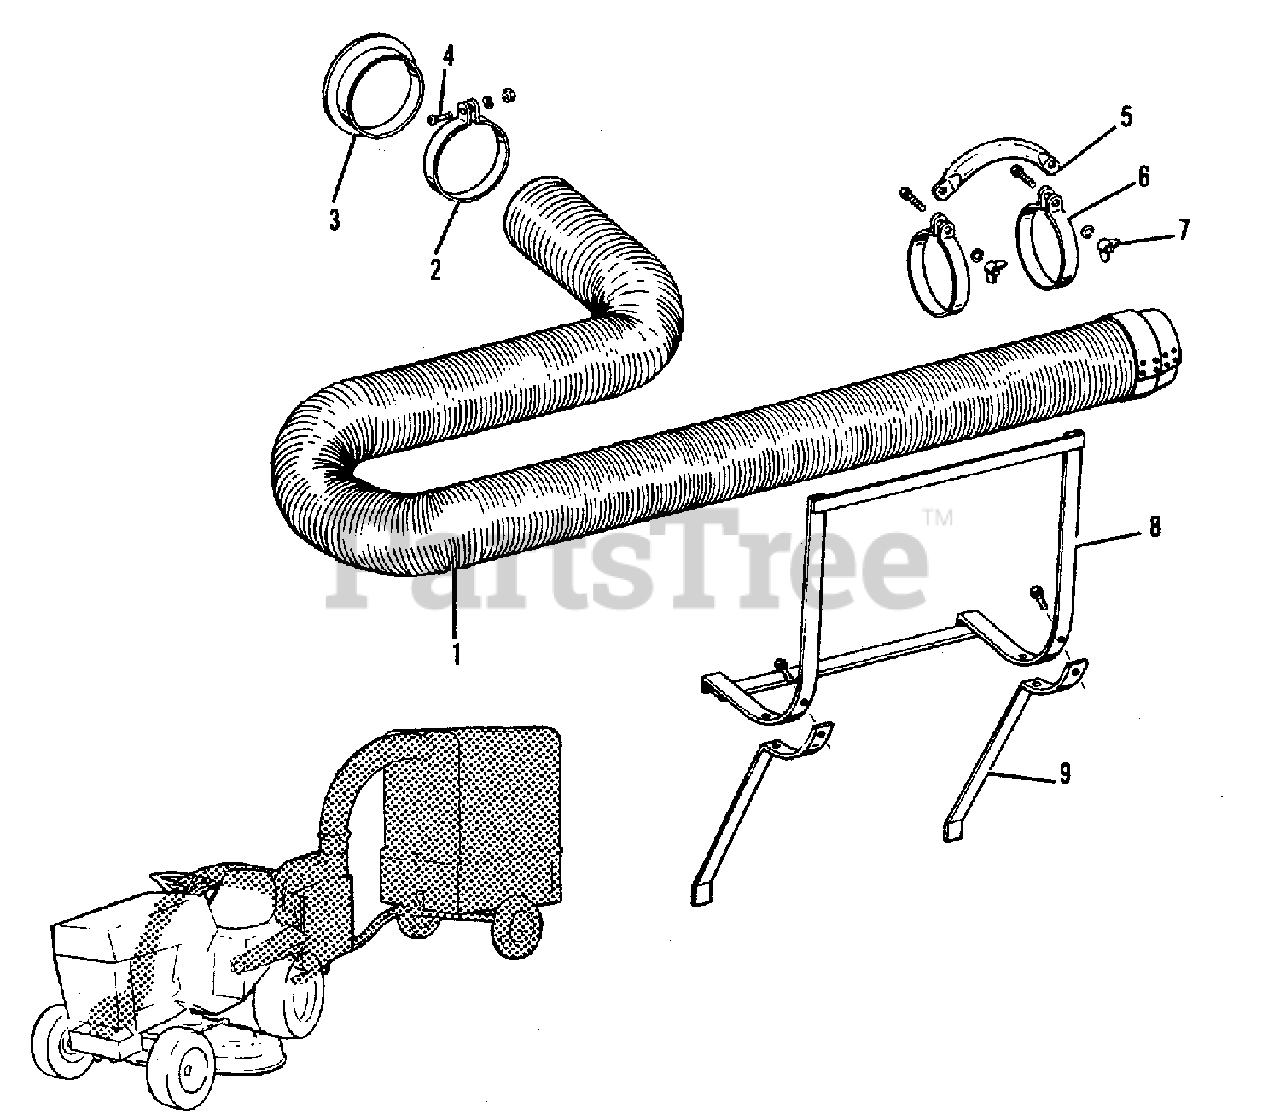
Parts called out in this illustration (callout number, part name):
1	HOSE ASSEMBLY
2	CLAMP, Hose
3	FLANGE, Hose
4	SCREW, Machine, Plated
4	LOCKWASHER, 1/4
4	NUT, 1/4NC
5	HANDLE, Hose
6	CLAMP, Hose Handle
6	CAPSCREW, 5/16NC x 3/4
6	LOCKWASHER, Plated, 5/16
7	NUT, Wing
8	CARRIER ASSEMBLY, Hose
8	CAPSCREW, 5/16NC x 7/8
8	WASHER, Plain, 5/16
8	LOCKWASHER, 5/16
8	NUT, 5/16NC
9	SUPPORT, Carrier
